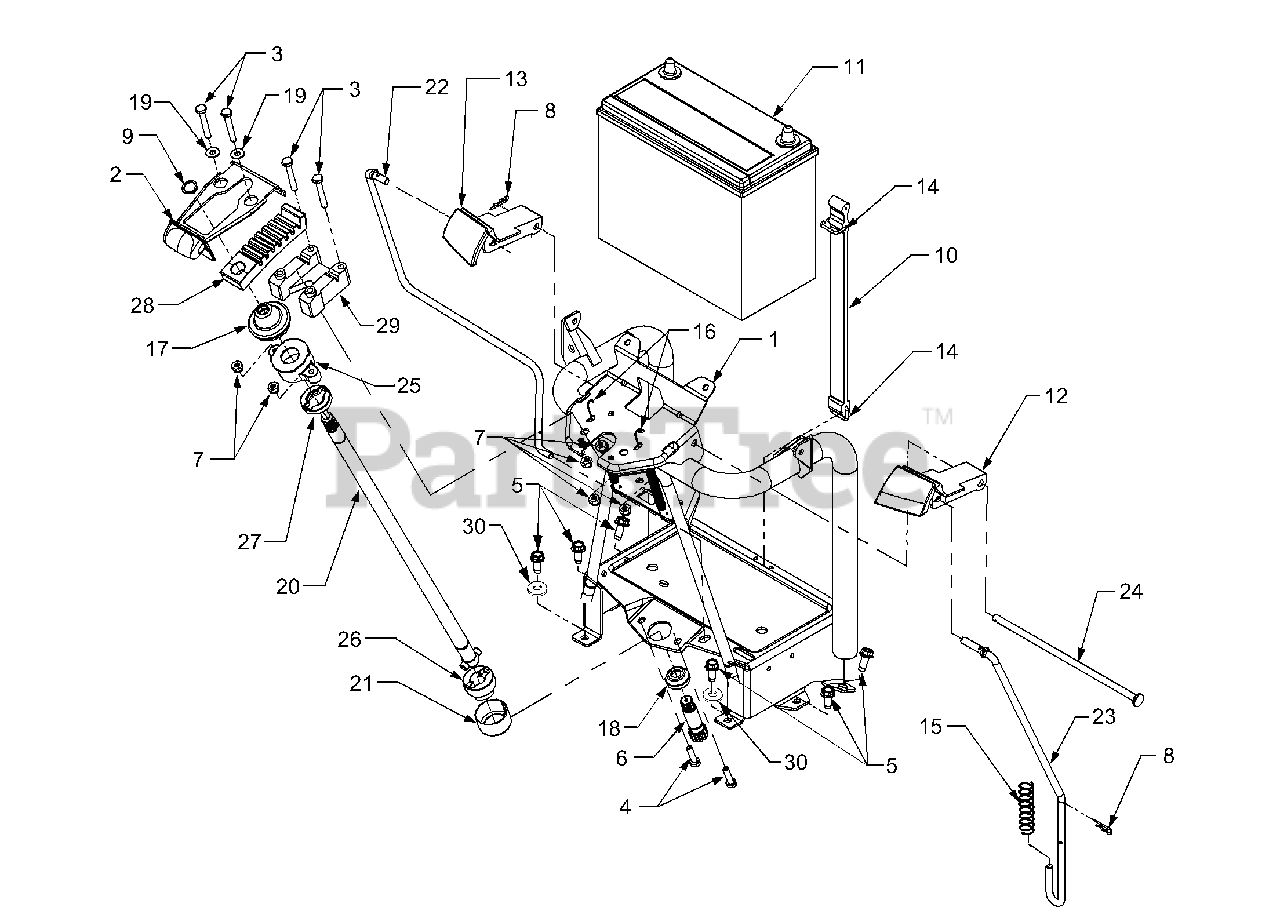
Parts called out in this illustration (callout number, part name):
1	Pedestal Assembly
2	Handle, Tilt
3	Screw, Hex Cap 1/4-20 x 1.75 GR5
4	Screw, Hex Cap 1/4-20 x 1.0 GR5
5	Screw, Hex Wash. Hd. Tapp 5/16-18 x .75
6	Shaft, Lower Steering
7	Nut, Hex Insert Lock, 1/4-20
8	Pin, Internal Cotter
9	Ring, Retaining, .56 Dia Shaft
10	Strap, Battery
11	Battery
12	Lever, Park Brake
13	Lever, Cruise
14	Hook, Wire Rectangular
15	Spring, Compression, .676 x 2.57
16	Spring, Extension
17	Boot, Tilt Wheel Coupling
18	Boot, Shaft Cover
19	Washer, Flat, .271 x .63 x .065
20	Shaft, Upper Steering
21	Bearing, Sleeve, 1.44 x 1.5 x .812
22	Rod, Cruise Control
23	Rod, Parking Brake
24	Rod, Cruise/Brake Pivot
25	Housing, Tilt Wheel Coupling
26	Coupling Half, Bottom
27	Coupling Half, Top
28	Index, Tilt Steering
29	Block, Tilt Steering
30	Washer, Flat, .344 x .688 x .065
